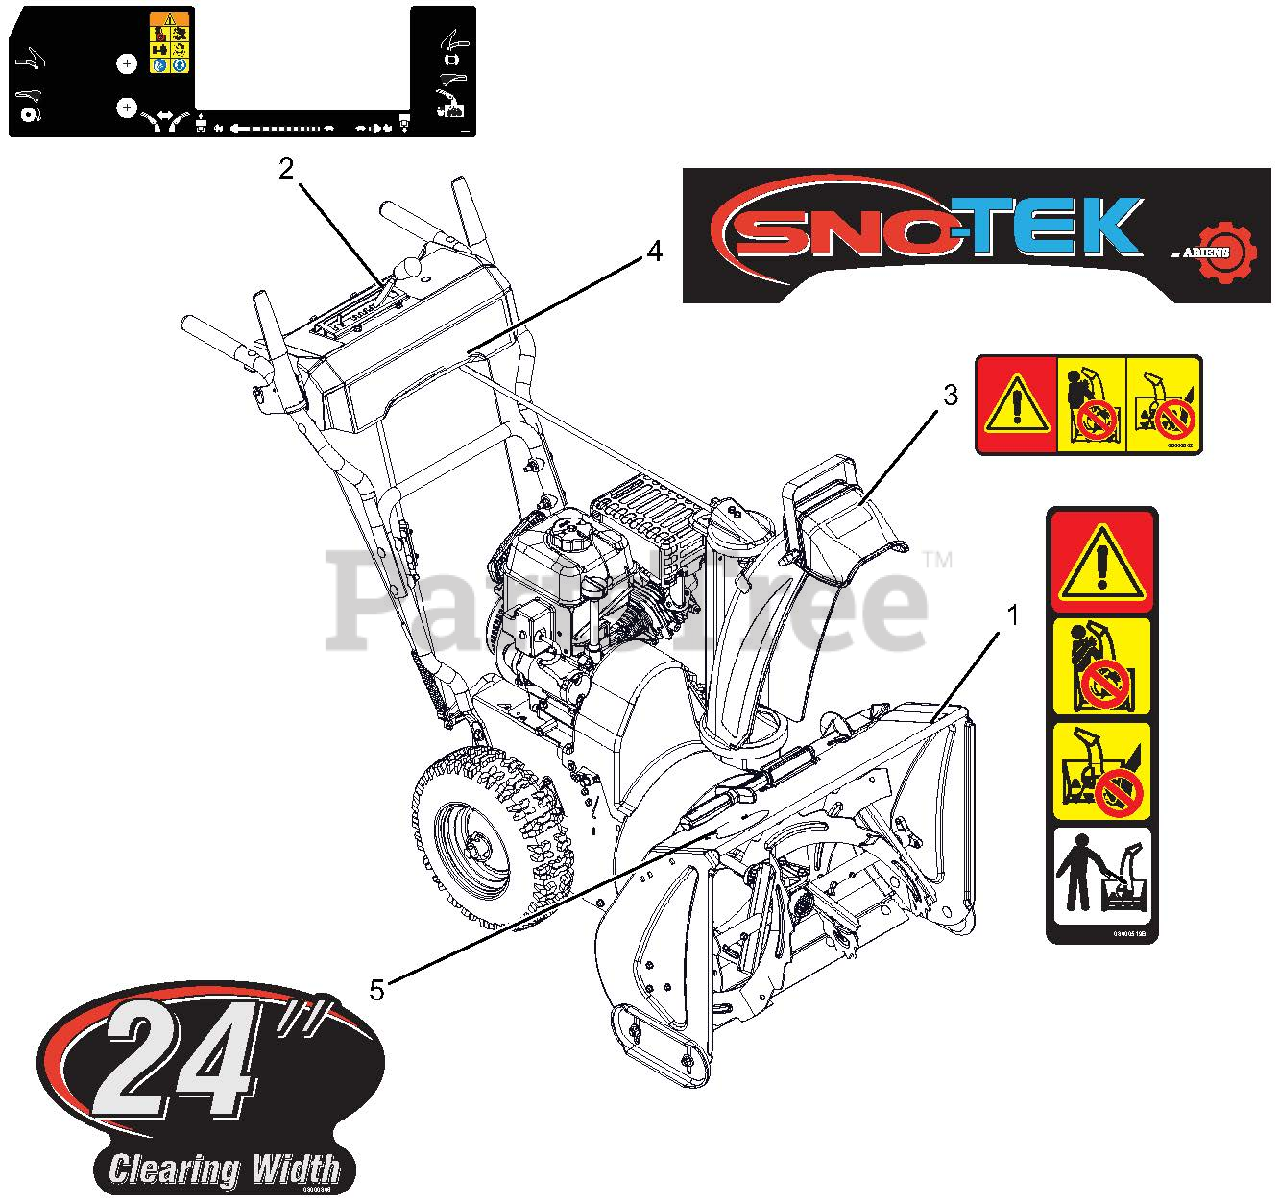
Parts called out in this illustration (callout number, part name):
1	DECAL, DANGER - ROTATING PARTS
2	DECAL,CONTROL - COMPACT MANUAL
3	DECAL, DANGER SNO-TEK
4	DECAL, DASH - SNO-TEK
5	DECAL, HOUSING SNO-TEK 24
